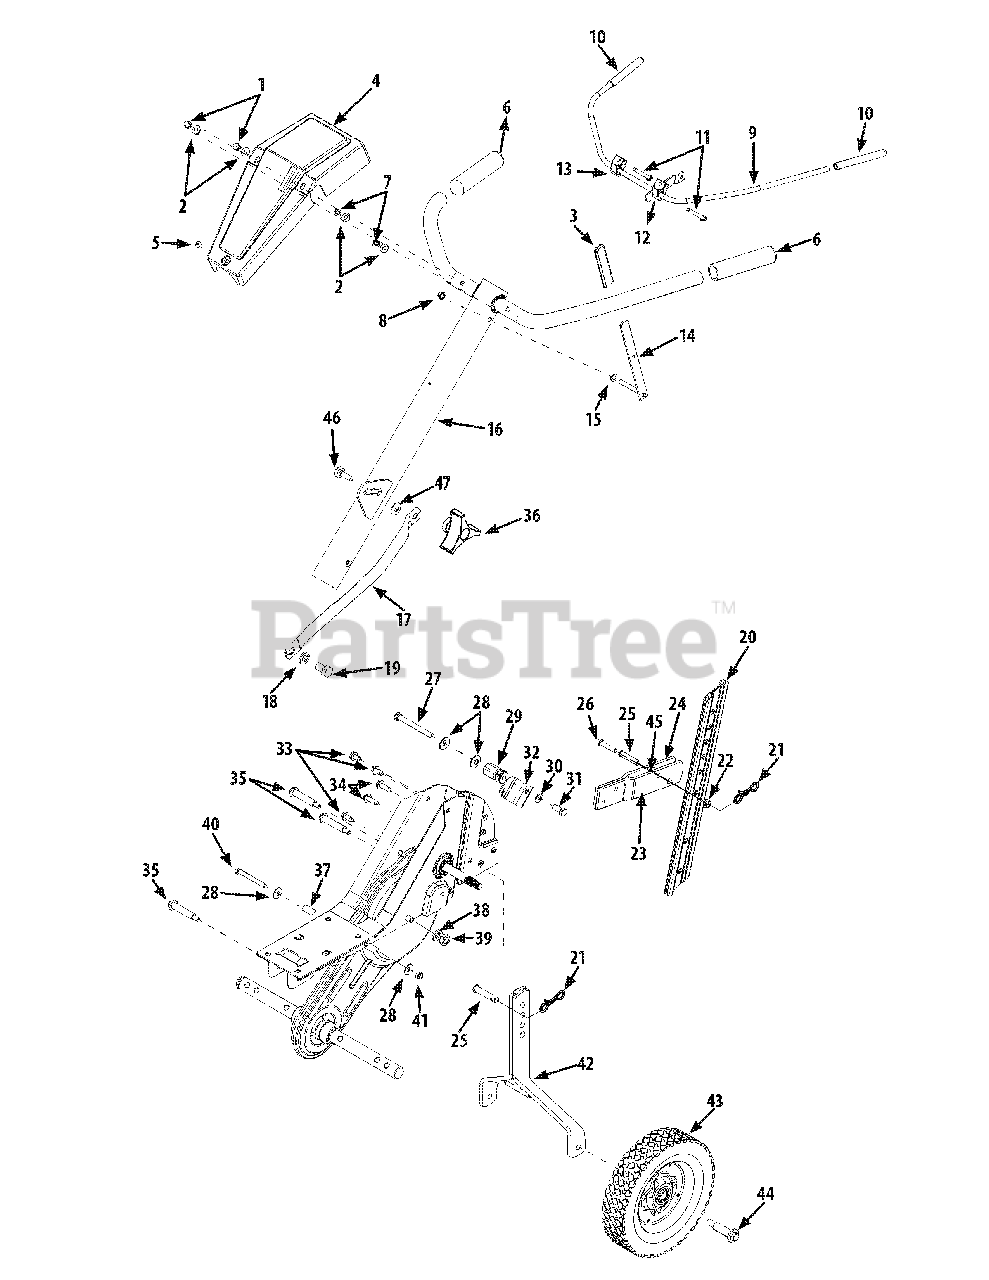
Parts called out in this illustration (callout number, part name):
1	Acorn Lock Nut, 1/4-20
2	Flat Washer, .271" x.630"
3	Reverse Handle Grip
4	Handle Cover w/o throttle
5	Truss Machine Screw, #10 x 1/2"
6	Handle Grip
7	Hex Nut, 1/4-20
8	Cap Speed Nut
9	Clutch Handle Assembly
10	Clutch Grip
11	Hex Bolt, 1/4-20 x 2.25"
12	Clutch Handle Holder
13	Flat Washer, .385" x .62"
14	Reverse Handle Assembly
15	Flat Washer, .344" x .62"
16	Handle Assembly Complete
17	Handle Brace
18	Lock Washer, 1/2
19	Hex Bolt, 1/2-20
20	Depth Bar
21	Cotter Pin, Bow Tie
22	Hex Flange L-Nut, 5/16-18
23	Tail Piece Bracket, Left
24	Tail Piece Bracket, Right
25	Clevis Pin
26	Hex Bolt, 5/16-18 x 1.5"
27	Hex Bolt, 5/16-18 x 3"
28	Bell Washer, .340" x .872"
29	Hex Nut
30	L-Washer, 5/16"
31	Hex Bolt, 5/16-18
32	Cable Guide Bracket
33	Hex Washer Screw, 5/16-18 x .62"
34	Hex Washer TT-Tap Screw
35	Shoulder Bolt, 5/16-18
36	Hand Knob
37	Spacer
38	Lock Washer, 7/16
39	Jam Nut, 7/16-20
40	Hex Bolt, 5/16-18 x 2.75"
41	Nylon Hex Nut, 5/16-18
42	Wheel Hanger Bracket Assembly
43	Wheel, 8 x 1.75
44	Shoulder Screw, .496 x 1.445
45	Spacer
46	Carriage Bolt, 5/16-18 x 1
47	Bell Washer, .34"
